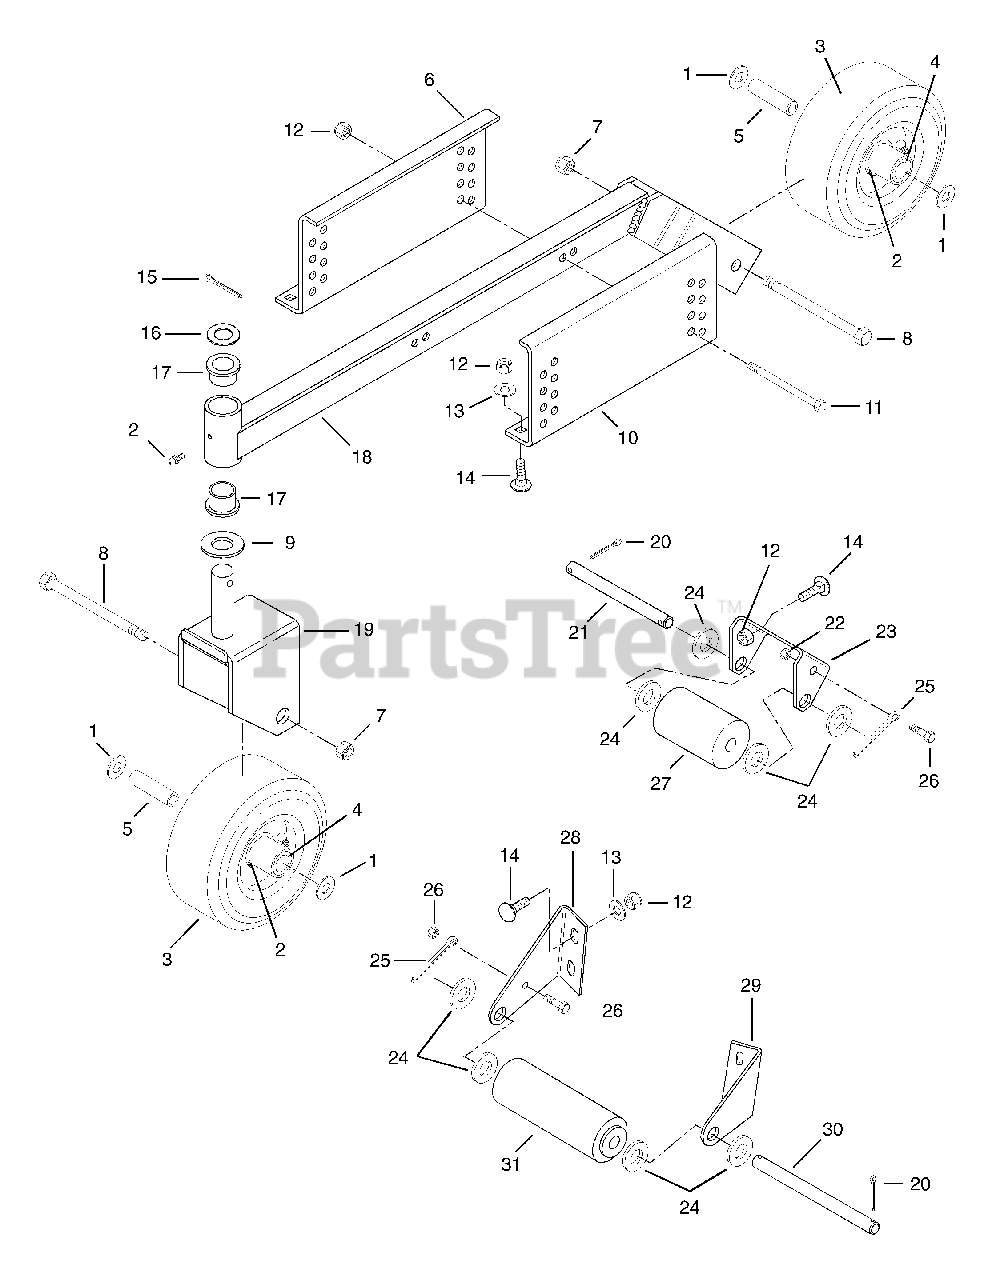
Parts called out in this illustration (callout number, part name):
1	Washer - Flat - Steel .531 x 1.250 x .100
2	Fitting - Lube .25-28 x .256
3	Wheel 9 x 3.50
4	Bearing-Ball .752 x 1.50 x .50
5	Spacer .532 x .748 x 3.34
6	Hanger-Left Hand
7	Nut-Locking-Nylon .50-13 Grade 5
8	Bolt-Hex .50-13 x 5.00
9	Washer-Flat-Steel 1.007 x 1.542 x .062
10	Hanger-Right Hand
11	Bolt-Hex .38-16 x 2.50 Grade 5
12	Nut-Locking-Nylon .375-16 Grade 2
13	Washer-Flat-Steel .406 x .812 x .065
14	Bolt-Round Head Square Neck .38-16 x 1.0
15	Pin-Cotter .188 x 1.625
16	Washer-Hardened-Thrust 1.00 x 1.55 x .030
17	Bushing-Flange 1.020 x 1.385 x .75 x 1.75
18	Weldment-Caster Wheel Support
19	Weldment-Caster Fork
20	Pin-Cotter .25 x 1.00
21	Rod
22	Nut-Hex .250-20 Grade 2
23	Bracket-Roller
24	Washer-Flat-Steel .656 x 1.312 x .095
25	Pin-Cotter .250 x 2.00
26	Bolt-Hex .25-20 x .75 Grade 5
27	Roller-Gage
28	Bracket-Roller Right Hand
29	Bracket-Roller Left Hand
30	Shaft-Center Roller
31	Roller-Gage
